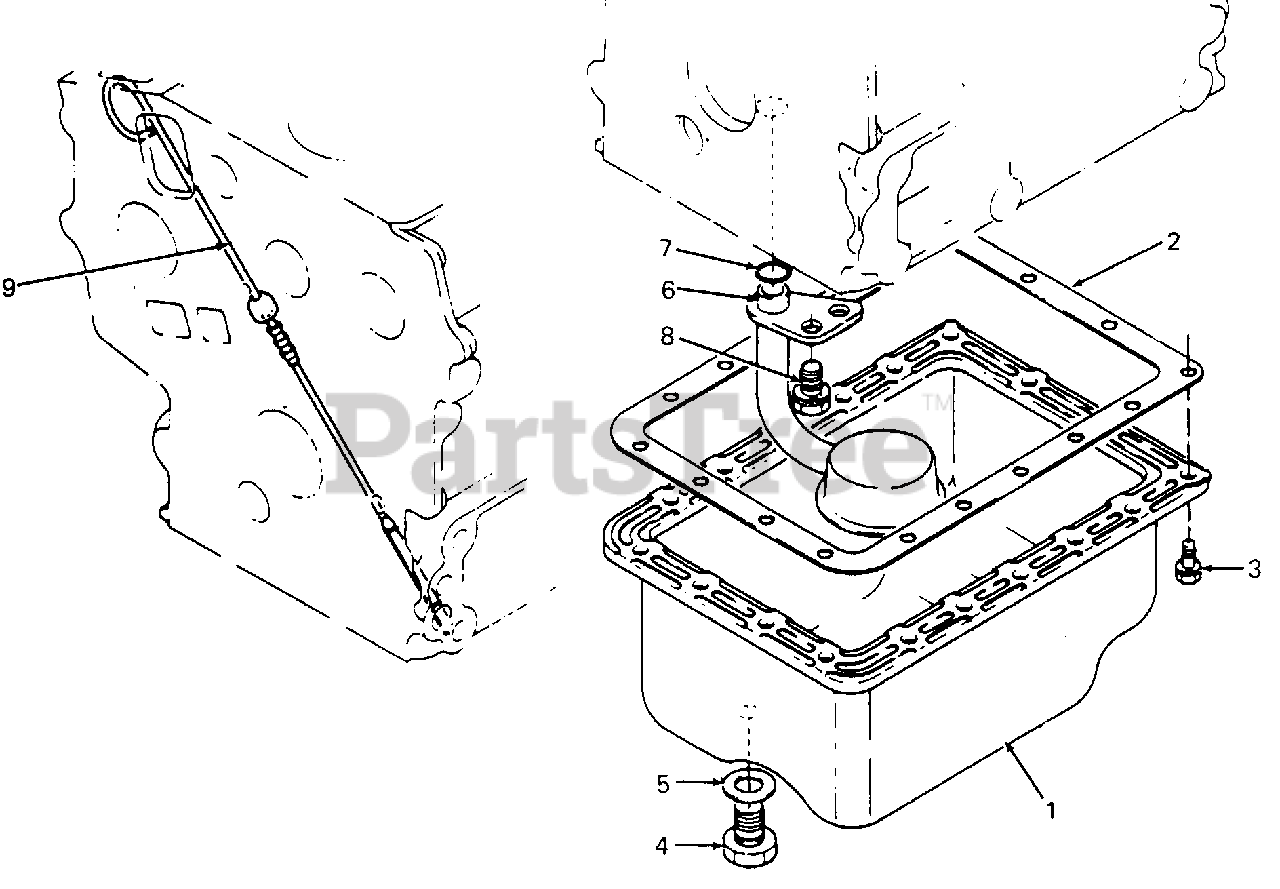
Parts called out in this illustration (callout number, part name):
2	Gasket, Oil Pan
3	Screw, Hex Cap w/Washer
5	Gasket
7	O-Ring
8	Screw, Hex Cap w/Washer
